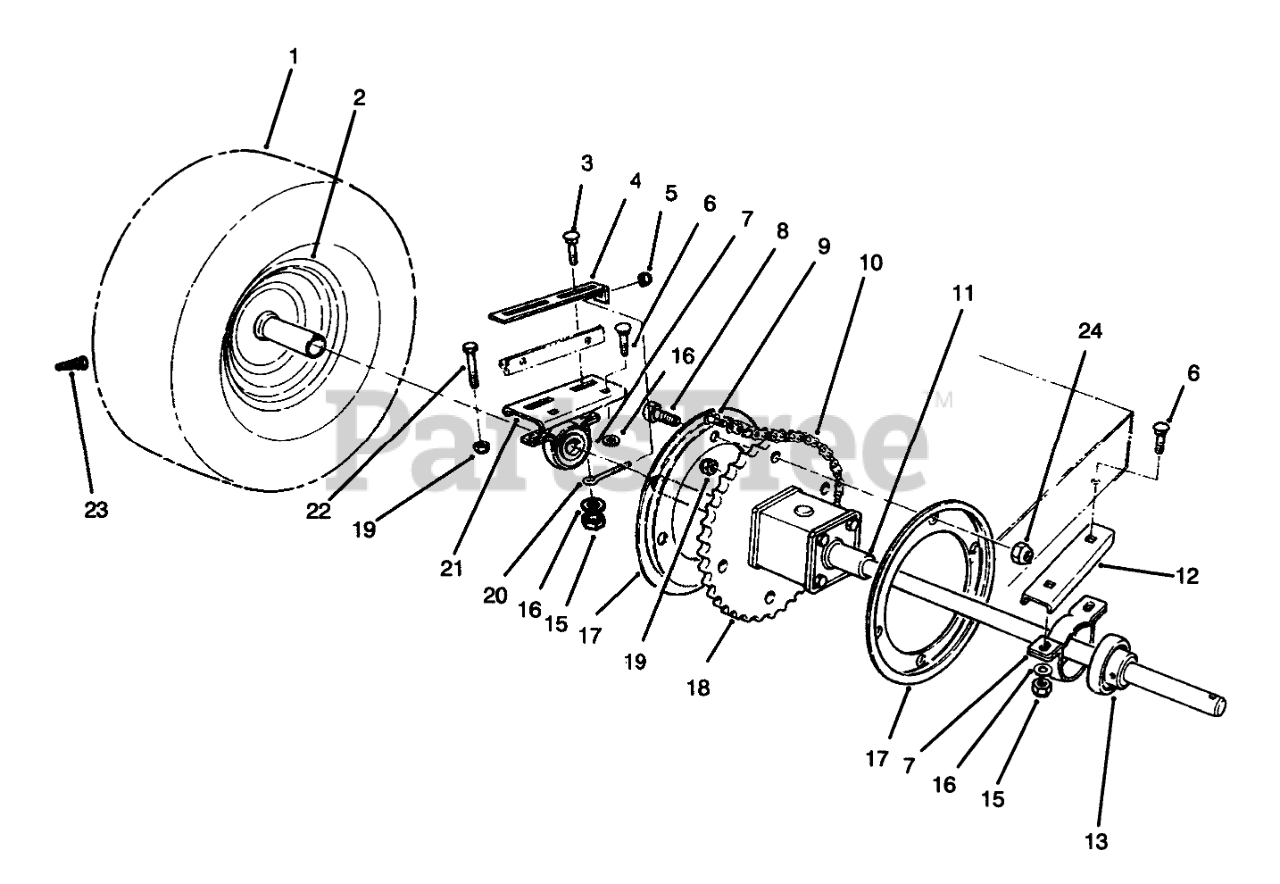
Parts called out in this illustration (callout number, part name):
1	TIRE,PNEU.13X5.00X6
2	WHEEL-REAR
3	SCREW-CARR
4	PLATE-ADJUSTING
5	NUT-LOCK, NI
6	BOLT-CARR
7	RTNR-PILLOW BLK
8	SCREW-HH
9	LINK-CHAIN
10	Chain (Incl. Ref. #9)
11	DIFFERENTIAL
12	LH AXLE SUPPORT (BLACK)
13	Bearing (Incl. Ref. #14)
15	NUT-LOCK, NI
16	WASHER-FLAT
17	GUIDE-REAR CHAIN
18	SPROCKET
19	NUT-LOCK, NI
20	SCREW-ADJUSTING
21	RH AXLE SUPPORT (BLACK)
22	AXLE MTG BOLT
23	STEM-VALVE
24	NUT-HEX
